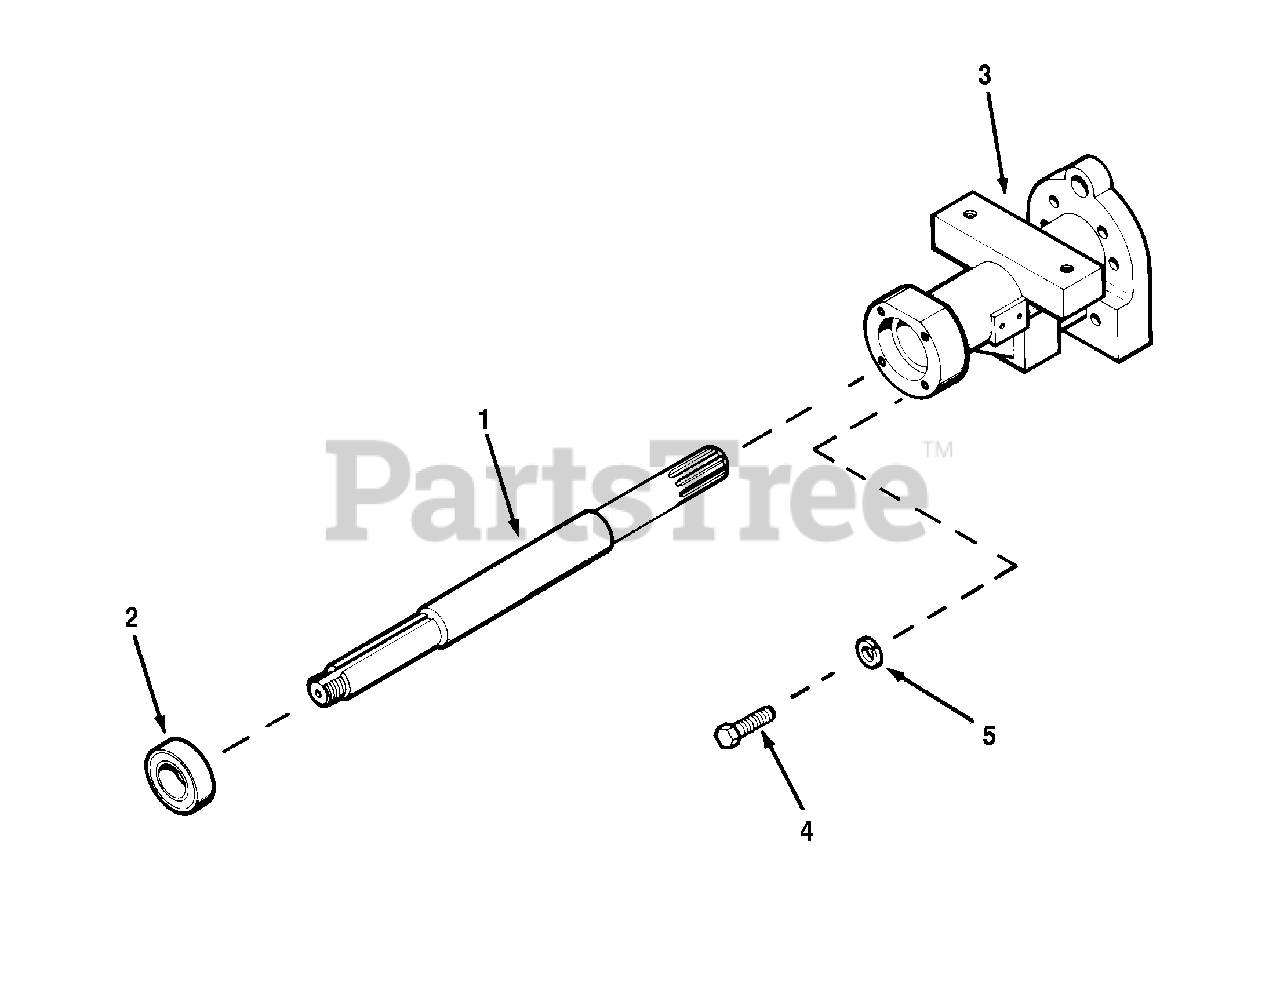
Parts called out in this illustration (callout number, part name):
1	Axle, 16-5/16" long
2	Ball Bearing
3	Axle Housing
4	Screw, 3/8-16 x 3/4"
5	Flat Washer, 3/8"
